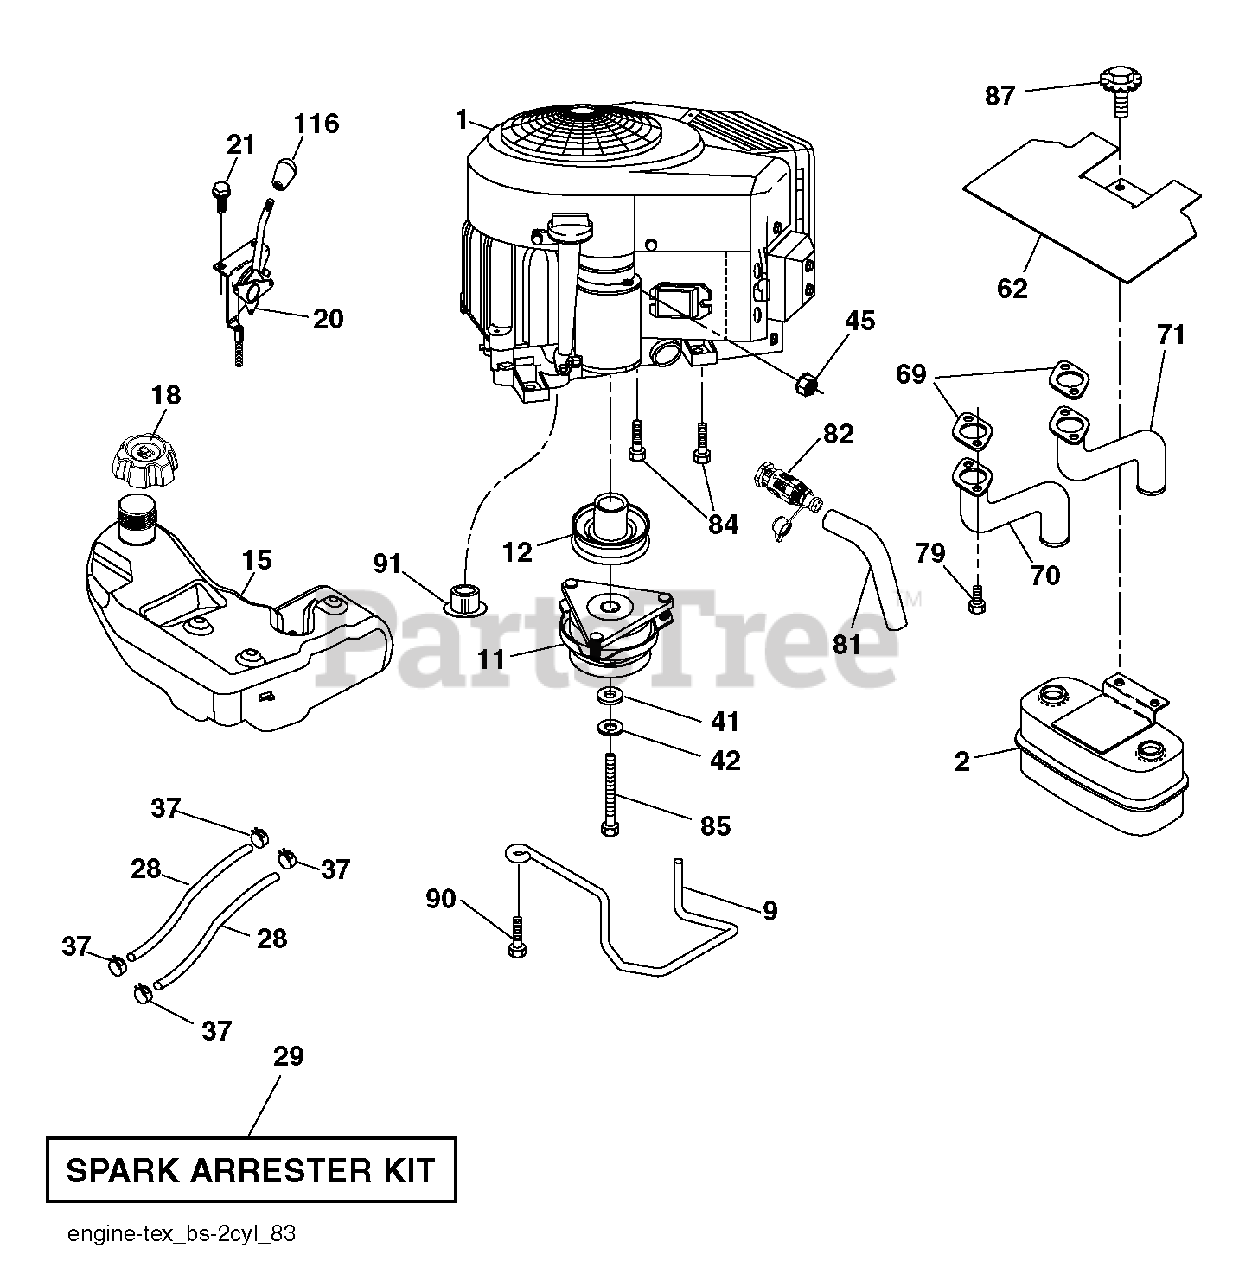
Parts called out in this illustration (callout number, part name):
2	MUFFLER.TWIN.CYL.LOW.TONE
9	KEEPER BELT ENGINE
11	CLUTCH ELECTRIC
12	PULLEY ENGINE
15	TANK.ASM.4.GAL.EPA
18	CAP ASM.FL.RTCHT.3"GRY.E10
20	Throttle and Choke Control
21	SCREW.#10 X 0.750.BOS THREAD
28	LINE.FUEL.64"REAR.EMIS
29	ARRESTER SPARK (OPTIONAL)
37	HOSE CLAMP
42	LOCKWASHER
45	NUT
62	SHIELD.HEAT.MUFFLER
69	GASKET.MUFFLER
70	Exhaust Tube, LH.Bs/Twin
71	Exhaust Tube, RH B&S Twin Intek
79	SCREW.SOCKET.HEAD.5/16-18
81	TUBE, DRAIN OIL ASM.
82	VALUE.OIL.DRAIN
84	SCREW.3/8-16
85	BOLT HEX 7/16-20 X 3.75 GR. 5
87	BOLT.5/16-18UNCX1.W/SEMS.BLK
90	SCREW 3/8-16X1
91	BUSHING.1.375OD
116	KNOB - SHIFT
